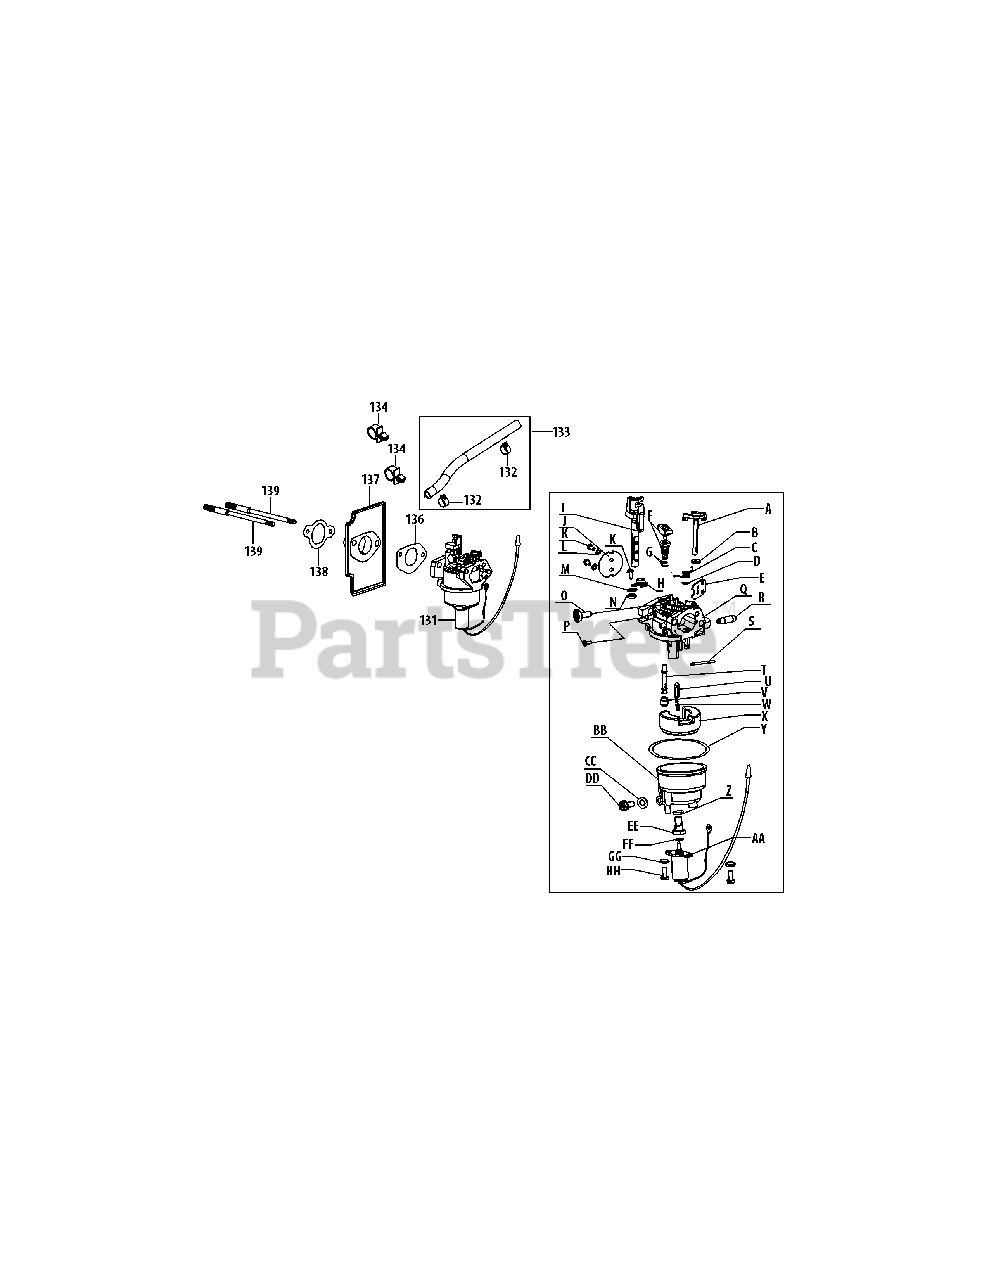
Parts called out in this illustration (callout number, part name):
131	Carburetor Assembly
132	Fuel Hose Clamp
133	Fuel Line Kit
134	Plastic Support Clamp
136	Carburetor Gasket
137	Carburetor Insulator
138	Carburetor Insulator Gasket
A	Choke Shaft
B	Fiber O-Ring
C	Choke Return Spring
D	Flat Steel Washer
E	Choke Plate
F	Idle Jet Assembly
G	Idle Jet O-Ring
H	Sheetmetal Housing
I	Throttle Shaft
J	Throttle Plate
L	Lock Washer
M	Nylon Plastic O-Ring
N	Fiber O-Ring
O	Idle Speed Adjusting Screw
P	Idle Mixture Screw
Q	Carburetor Body
R	Fuel Inlet
S	Float Pin
T	Emulsion Tube
U	Needle Valve
V	Main Jet
W	Needle Valve Spring
X	Float Pin
Y	Fuel Bowl O-Ring
Z	Seat/Fuel Bowl Bolt O-Ring
AA	Solenoid Valve Assembly
BB	Fuel Bowl
CC	Fuel Drain Plug Gasket
DD	Fuel Drain Plug
EE	Seat/Fuel Bowl Bolt
FF	Solenoid Valve Assembly O-Ring
HH	Screw M5 X 10
